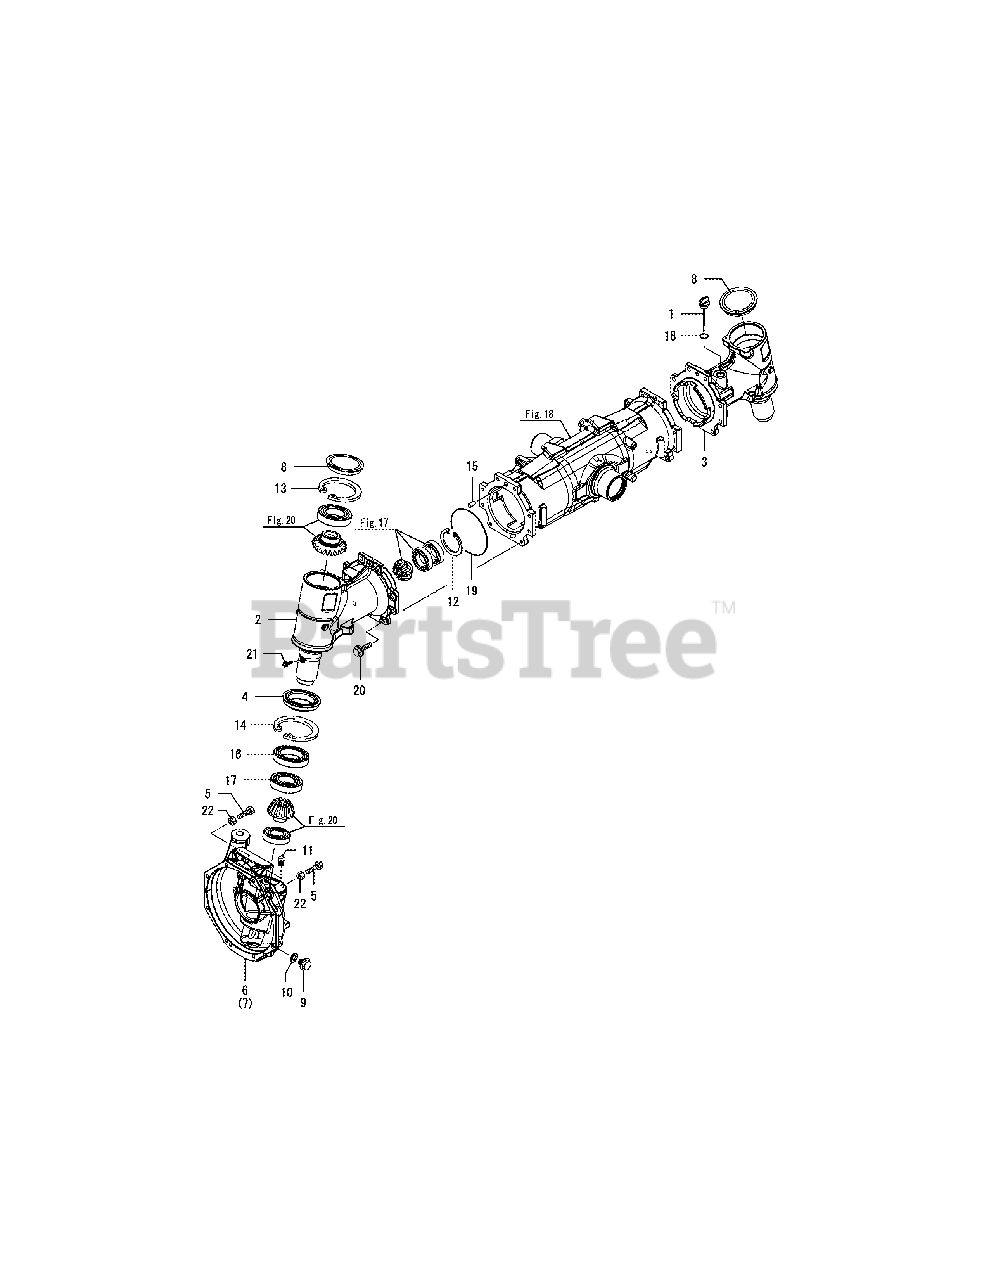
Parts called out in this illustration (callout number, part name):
2	HOUSING, FRONT GEAR
3	HOUSING, FRONT GEAR
6	GEARBOX, FRONT L
7	GEARBOX, FRONT R
8	CAP,SEALING 90
9	BOLT M14X10, DRAIN
15	PARALLEL PIN 10X 18
18	O-RING 1A P-18.0
19	O-RING 1A G-130.0
20	BOLT M10X 30 PLATED
22	LOCK NUT M10 PLATED
